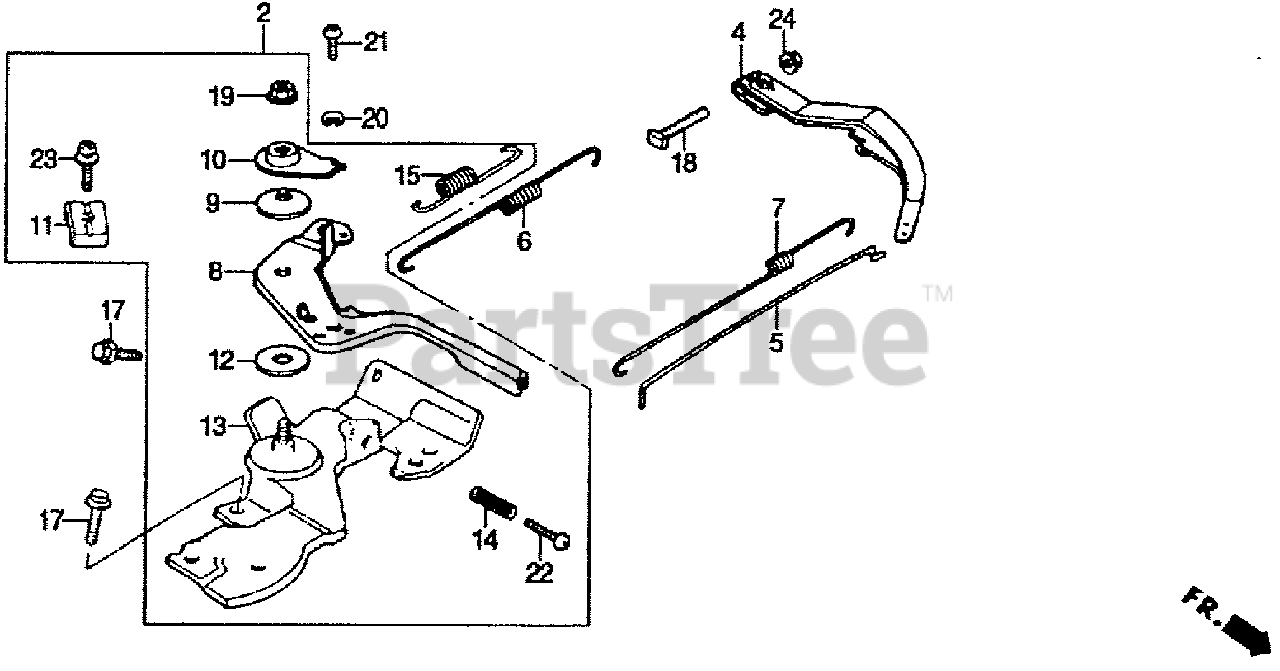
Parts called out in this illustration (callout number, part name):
2	CONTROL ASSY. (REMOTE)
4	ARM, GOVERNOR
5	ROD, GOVERNOR
6	SPRING, GOVERNOR
7	SPRING, THROTTLE RETURN
8	LEVER, CONTROL
9	SPRING, LEVER
10	WASHER, CONTROL LEVER
11	HOLDER, CABLE
12	SPACER, CONTROL LEVER
13	BASE, CONTROL (REMOTE)
14	SPRING, CONTROL ADJUSTING
15	SPRING, CABLE RETURN
17	BOLT, FLANGE (6X12) (CT200)
18	BOLT, GOVERNOR ARM
19	NUT, SELF-LOCK (6MM)
22	SCREW, PAN (5X20)
23	SCREW-WASHER (5X16)
24	NUT, FLANGE (6MM)
